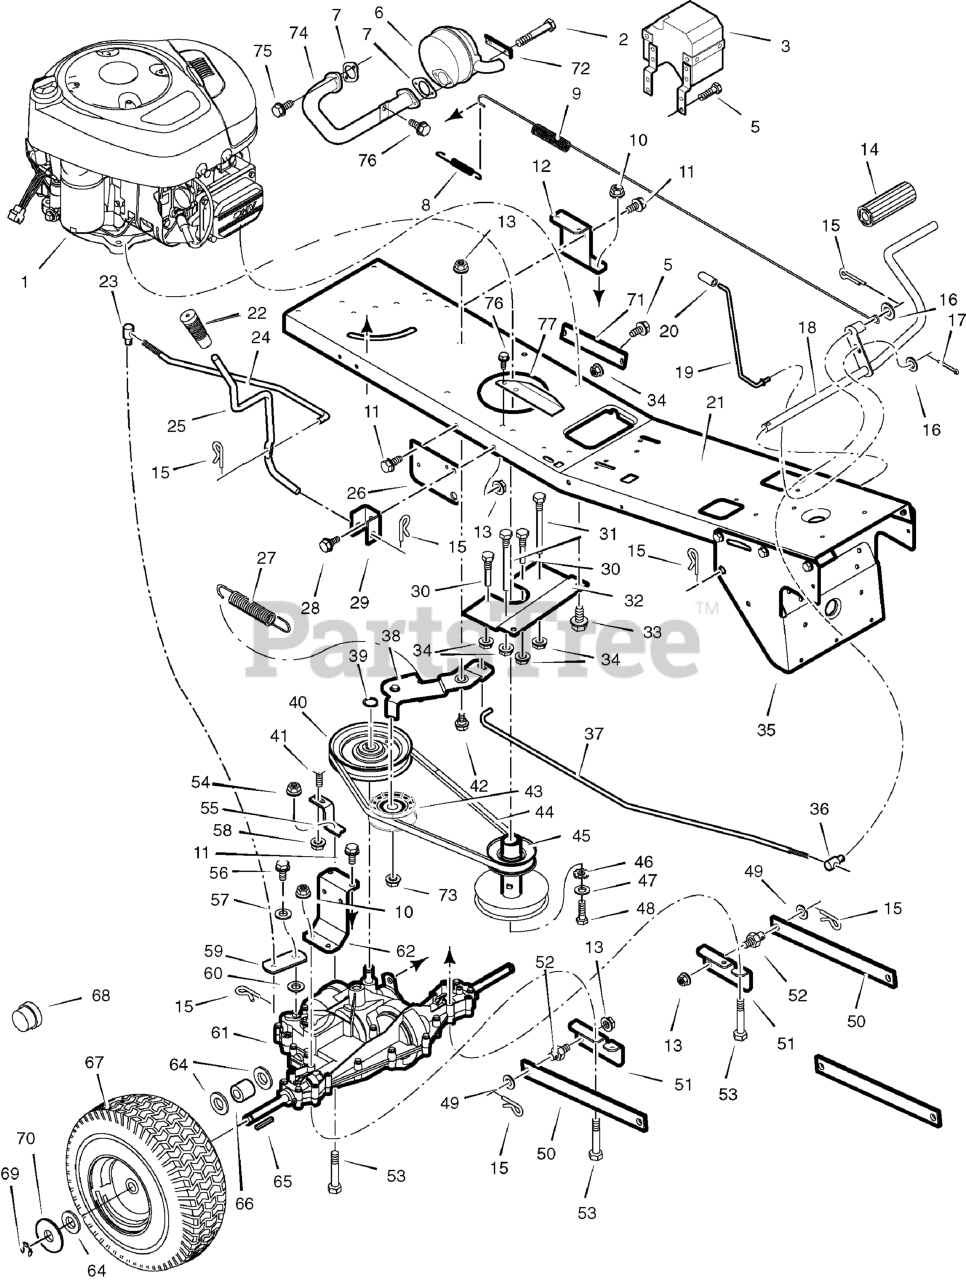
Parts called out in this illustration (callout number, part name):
1	Engine, Briggs & Stratton
2	Bolt, Hex
3	Shield Assembly, Heat
7	GASKET, Exhaust
8	Spring, Extension
9	Spring, Extension
10	Nut
12	Bracket, Left Transaxle
13	Nut, Flange
14	Cover, Pedal
15	Pin, Cotter
16	Washer
17	Pin, Cotter
18	Pedal Assembly
19	Rod, Parking Brake
20	Grip, Parking Brake Rod
22	Grip, Shift Lever
23	Nut, Adjusting
24	Link, Shift
25	Lever, Shift
26	Bracket, Lift Pivot
27	Spring, Extension
28	Bolt, Shoulder
29	Bracket, Pivot
30	Guide, Belt -Short
31	Guide, Belt -Long
32	Plate, Belt Guide *
33	Bolt
34	Nut, Flange
35	Bracket, Support
36	Nut, Adjusting
37	Rod, Clutch
38	Clutch Arm Assembly
39	Ring, Retainer
40	Pulley, Drive
41	Bolt, Carriage
42	Bolt, Shoulder
43	Pulley, Idler
44	Belt, Motion Drive
45	Pulley, Split Stack
46	Washer, Star
48	Bolt, Hex
51	Bracket, Rear Hanger
52	Pin, Threaded Shoulder
53	Bolt, Hex
54	Nut
55	Bracket, Torque Reactor
57	Washer, Shift Yoke
58	Nut
59	Yoke, Shift
61	Transaxle, Peerless **
62	Bracket, Right Transaxle
65	Key, Square
66	SPACER, Rear Wheel
67	Wheel, Rear -15"
68	Cap, Hub
71	Plate, Reinforcement
72	Lock, Screw
73	Nut
74	Tube, Exhaust
77	Shield, Heat
